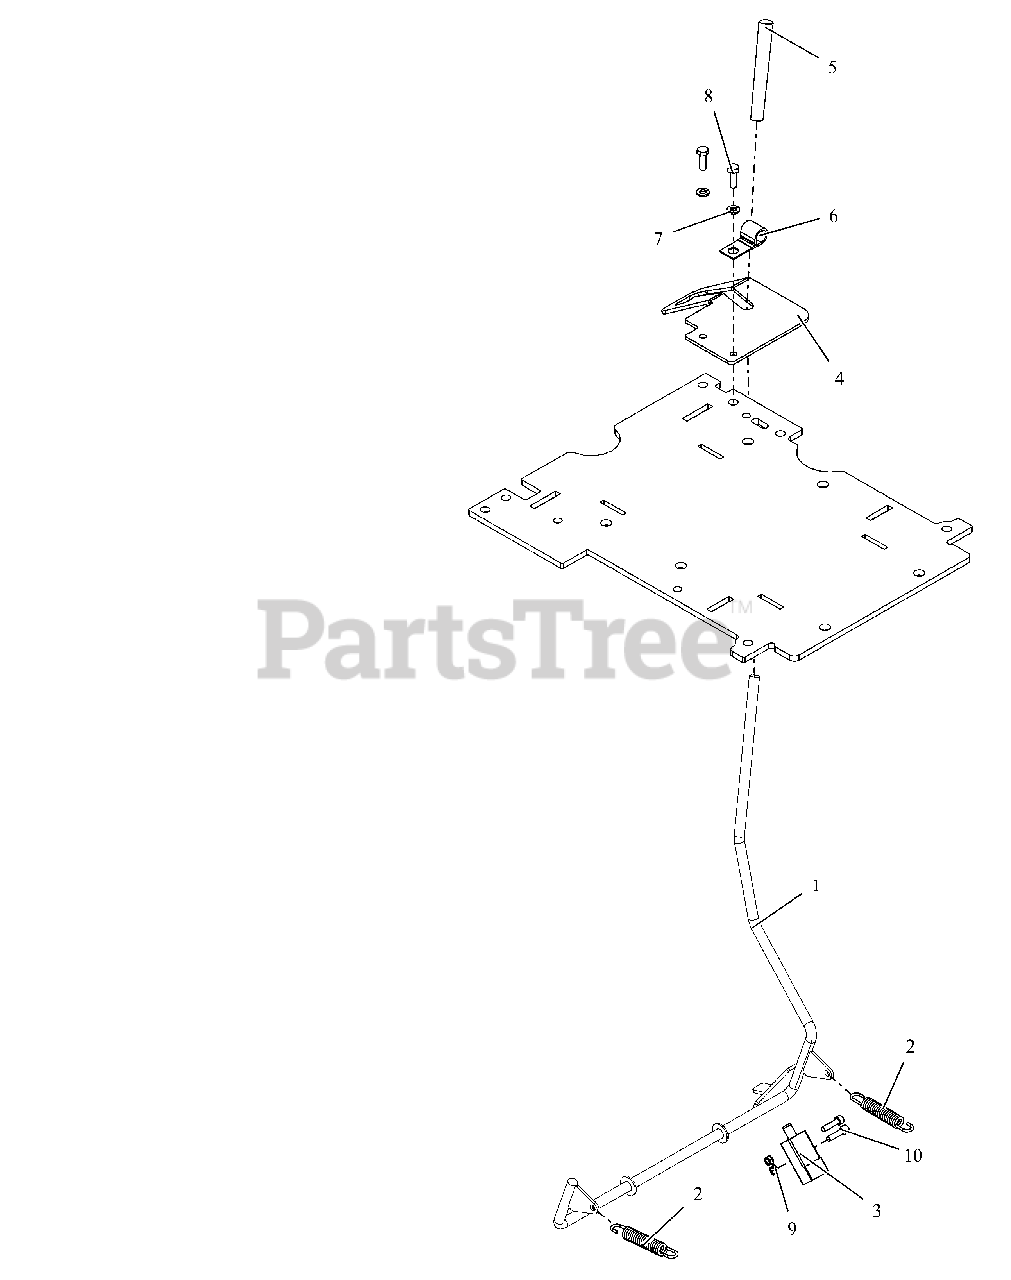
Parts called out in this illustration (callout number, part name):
1	WLDMT, LEVER BRAKE
2	SPRG, EXT .503 X .095 X 3.150
3	SWITCH,INTERLOCK
4	PLATE, BRAKE PROFILE
5	GRIP, PLASTIC
6	P-CLIP, .500 INSULATED
7	WSHR,LK-REG .250X.062 ZCC
8	BLT, HEX M6-1.0 X 20 G8.8 ZCC
9	NUT, KEPS M5-.8 G8.8 ZCC
10	SCR, SKH M5-.8X20 12.9ZC120
